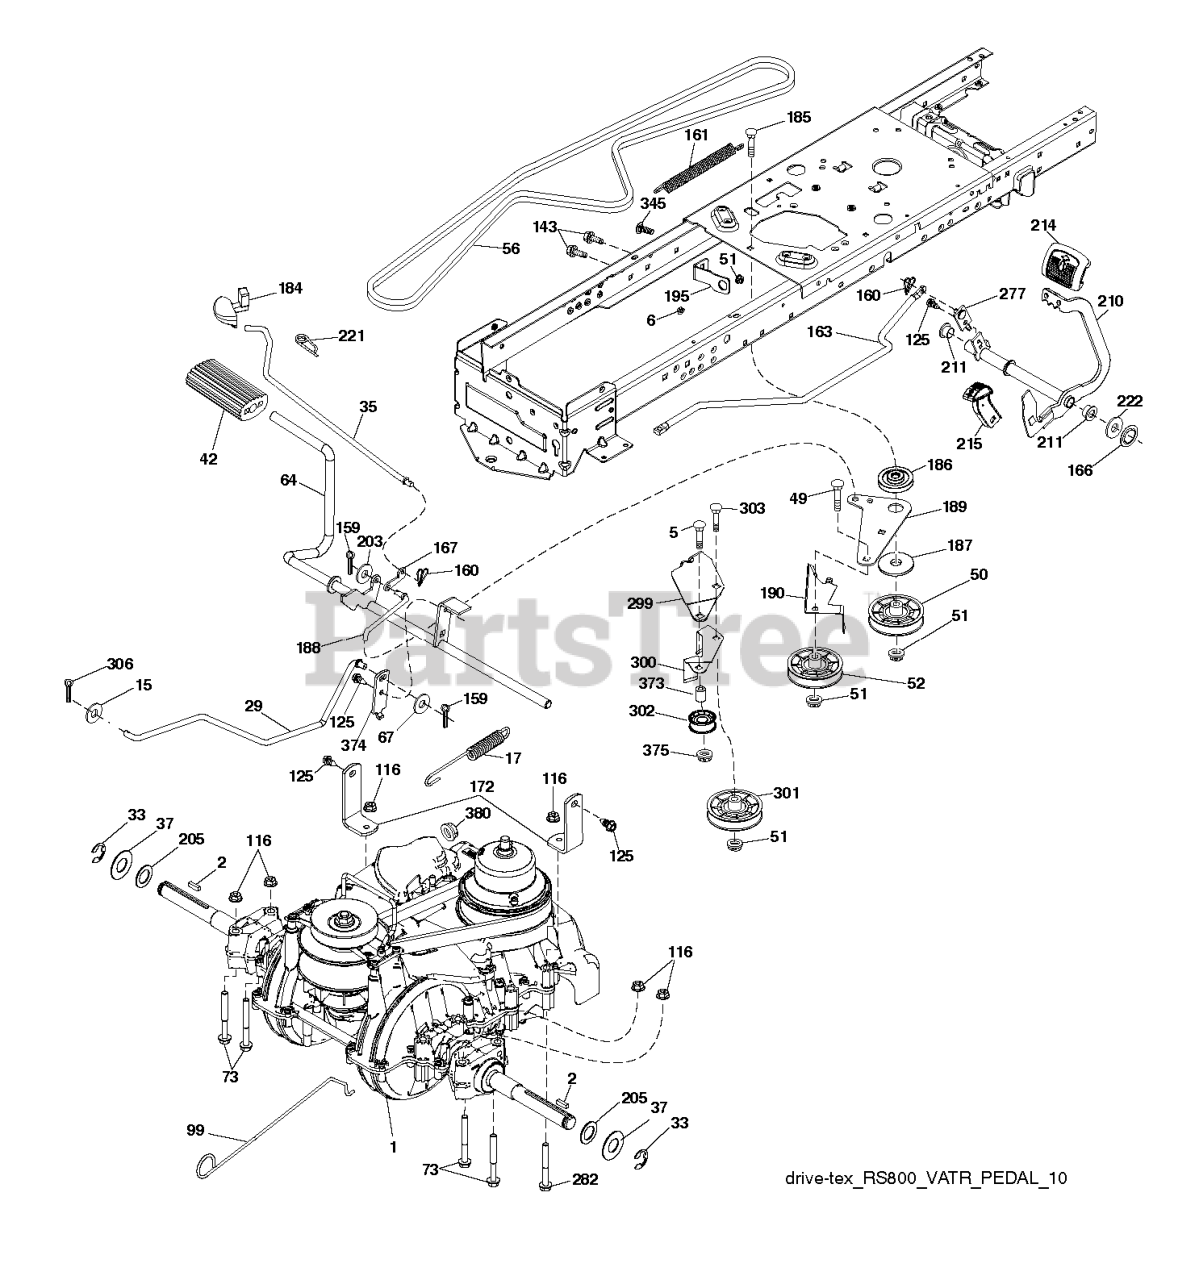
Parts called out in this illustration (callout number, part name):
2	SQUARE KEY
6	BUSHING.SNAP.NYL.BLK.
15	WASHER
17	SPRING BRAKE VARIATOR
29	BRAKE.VARIATOR.SD3
35	ROD.CNTRL.PARK.PREDATOR.LT.TEX
37	WASHER.HARDENED
42	PEDAL COVER T
49	BOLT
50	IDLER.FLAT.910.OFFSET
51	NUT LOCK FLG 3/8-16 UNC
52	IDLER.V-GROOVE.910.OFFSET
56	BELT.DRIVE.MOWER.TEX.42"
64	SUBASM.SHAFT.PEDAL.BRAKE
67	WASHER
73	BOLT HEX 5/16-18 GR 5
99	ROD.BYPASS.VARIATOR.GEN2
116	NUT LOCK HEX FLANGE 5/16-18
125	SCREW
143	SCREW LT
159	COTTER PIN
160	RETAINER CLIP
161	SPRING, RETURN LT
163	ROD.CONTROL.PEDAL.VARIATOR
166	NUT.PUSH.625
167	LATCH.BRAKE.SPRING
172	STRAP.TORQUE.VARIATOR
184	HANDLE.PARKNG BRK.PRED.LT.428
186	SPACER.RETAINER
187	WASHER 12/32X2X10GA
188	RP.LINK.CLUTCH.GROUND.DRIVE
189	BELLCRANK.GROUND.DRIVE.TEX.
190	KEEPER.BELLCRANK.DRIVE
195	BRACKET.BRAKE.BRAKE.VAR.SD
203	WASHER
210	WELDMENT.PEDAL.VARIATOR
211	BEARING.NYLON
214	PEDAL.FORWARD.PAD.TEX
215	CAP.PEDAL.REVERSE.VARIATOR
221	RETAINER.SPRING.CLIP.H
222	WASHER 21/32 X 1-1/4 X 10 GA.
277	SUBASM.LINK.ROCKER.PEDAL
282	BOLT HEX FLGHD 5/16-18X3 GR. 5
299	BRACKET.MOUNT.IDLERS
300	KEEPER.IDLERS.REAR.VARIATOR
301	PULLEY.IDLER.V-GROOVE
302	PULLEY.IDLER.FLAT.2"
303	BOLT CARRIAGE
306	PIN COTTER
345	BOLT
373	SPACER.IDLER
374	ARM.CONTROL.BRAKE
375	LOCKNUT
378	NUT.PUSH.8MM
